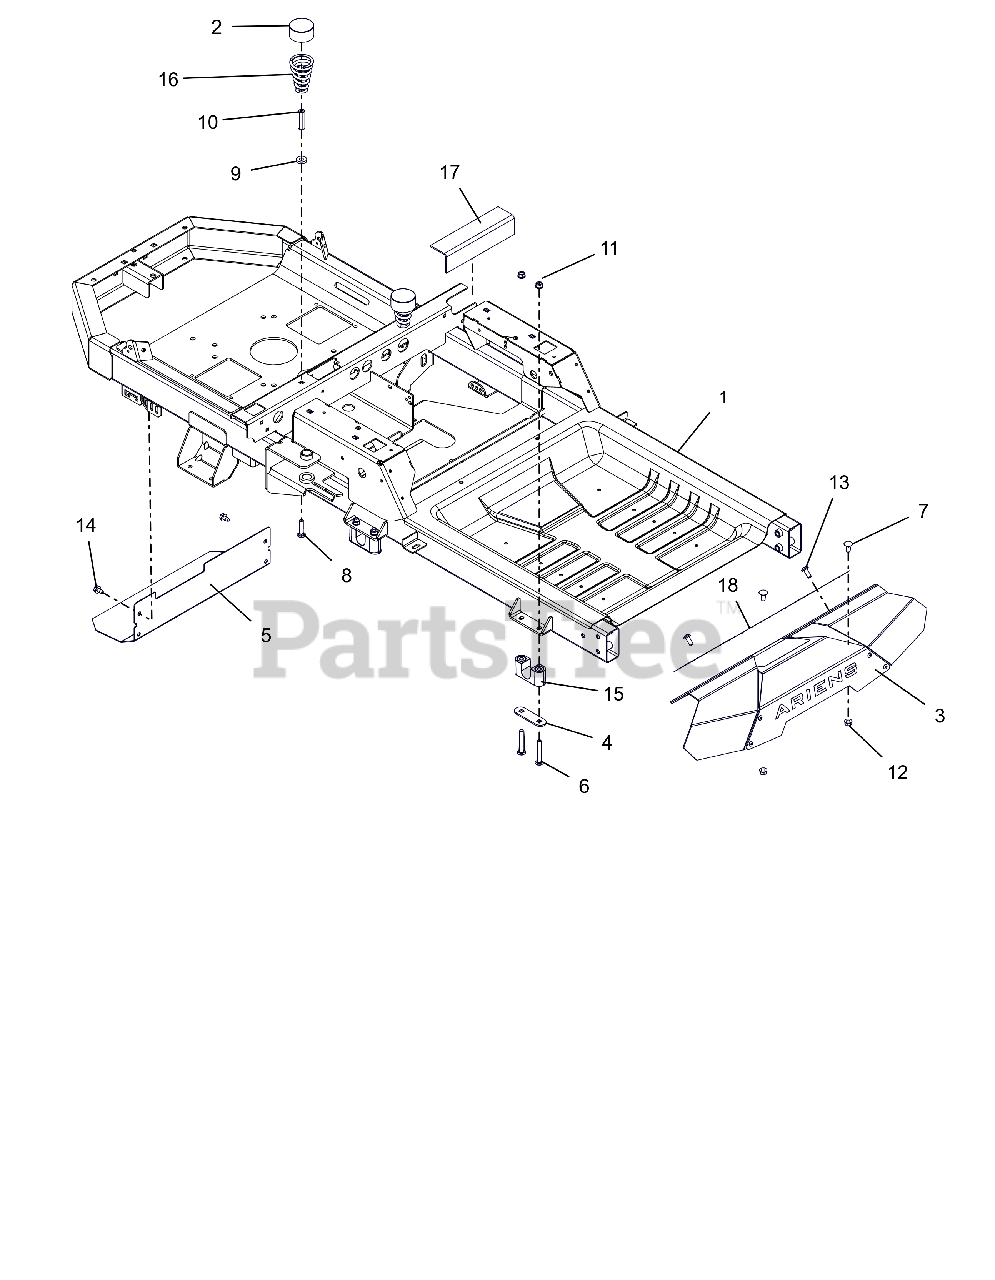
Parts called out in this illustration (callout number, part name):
1	KIT, IKON-X/XL FRAME (2016)
2	HUB CAP
3	KIT, IKON FOOT REST W/DECAL
4	PLATE, BEARING SUPPORT
5	HEAT, SHIELD
6	BLT-RDHDSQSHNK .31-18X2.25 YWZ
7	BLT,RHSN .31-18X.75 G5 ZCC
8	BLT,RHSN .31-18X1.50 G5 ZCC
9	WSHR, FLT .328X.870X.179 ZCC
10	NUT, COUPLING 5/16-18 X 1 3/4
11	NUT,LK-CTR-FLG .31-18 GF ZCC
12	NUT-LK-TOP-FLG .312-18 GF ZCC
13	SCR-RDHDSKTAP .31-18 X .75
14	SCR,TAP .312-18X.50 HWH TR ZCC
15	BSHG, DECK LIFT PIVOT
16	SPRING, SEAT
17	PAD, RUBBER-TANK
18	GRIP TAPE, FOOT PLATE
